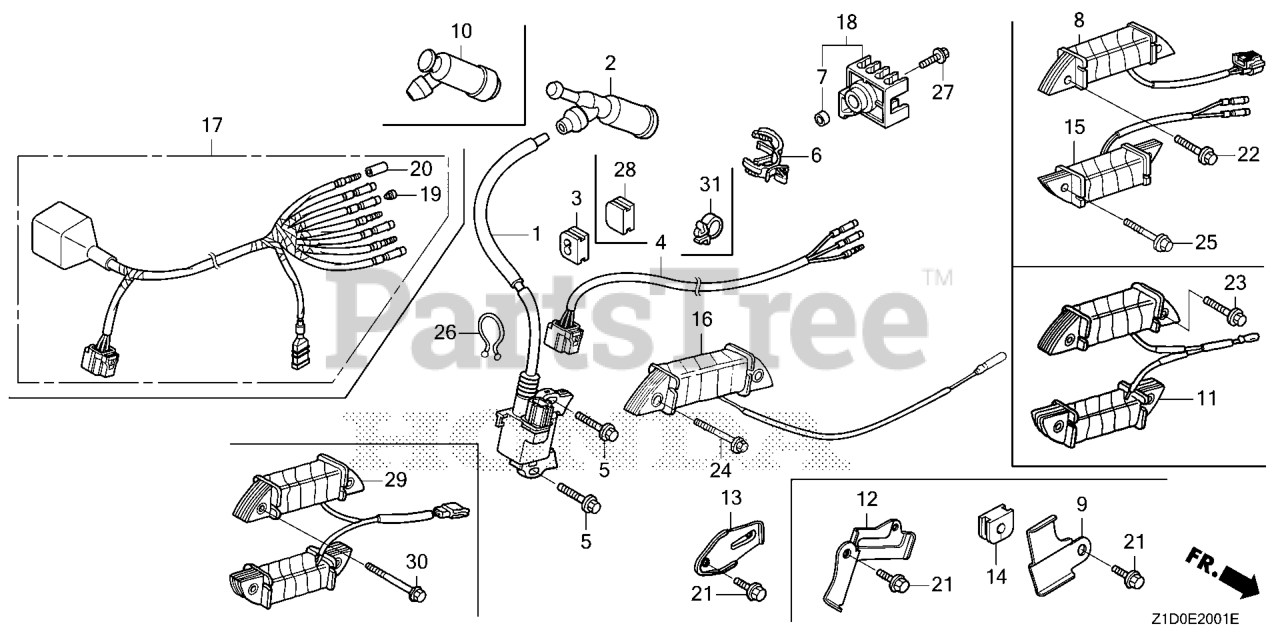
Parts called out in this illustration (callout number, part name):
1	COIL ASSY., IGNITION
2	CAP ASSY., NOISE SUPPRESSOR (NGK Y-EZD)
3	GROMMET, WIRE
4	WIRE HARNESS ASSY., ENGINE
5	BOLT, FLANGE (6X28) (CT200) Use up to Engine SN 1530314.
6	CLIP, WIRE HARNESS
